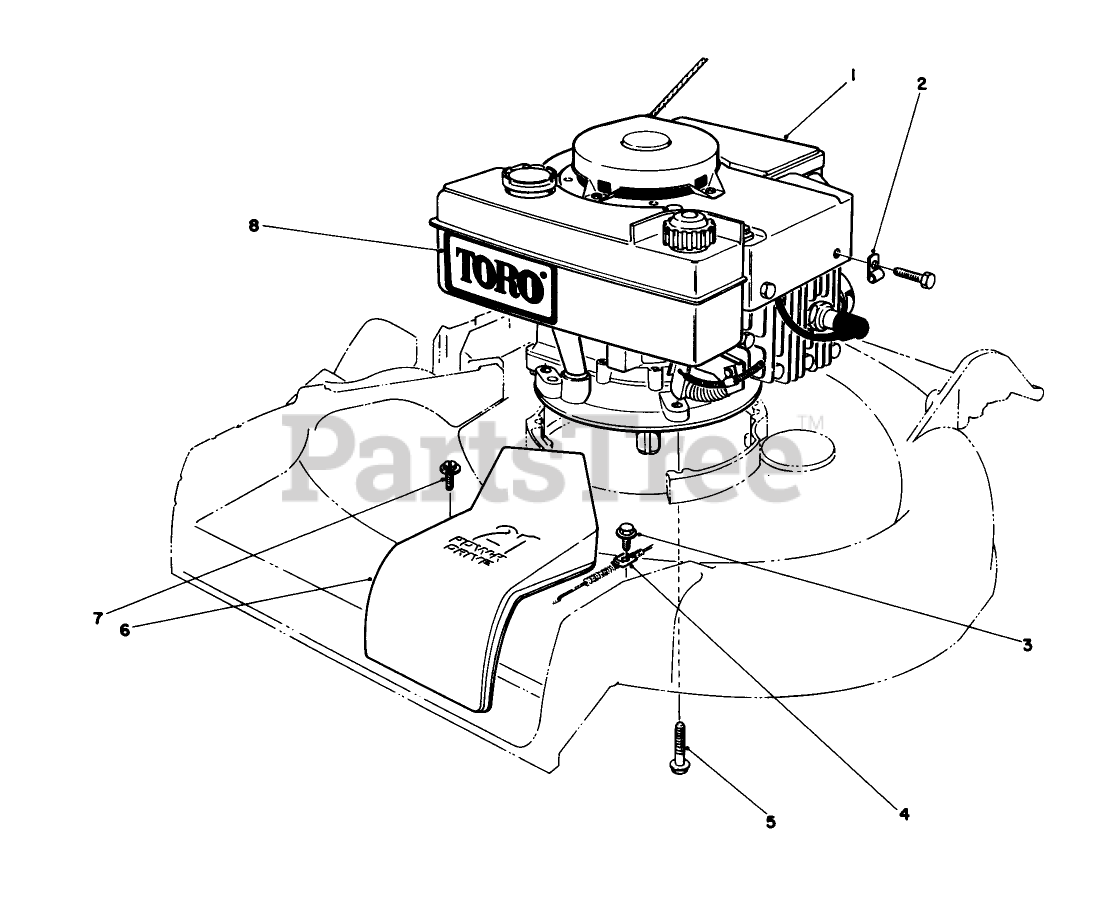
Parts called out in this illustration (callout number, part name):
1	Engine
3	SCREW-THD ROLL, HWH
5	3/8-16 X 2-3/4 CAPSCR
6	BELT COVER 21" S D
7	SCREW
